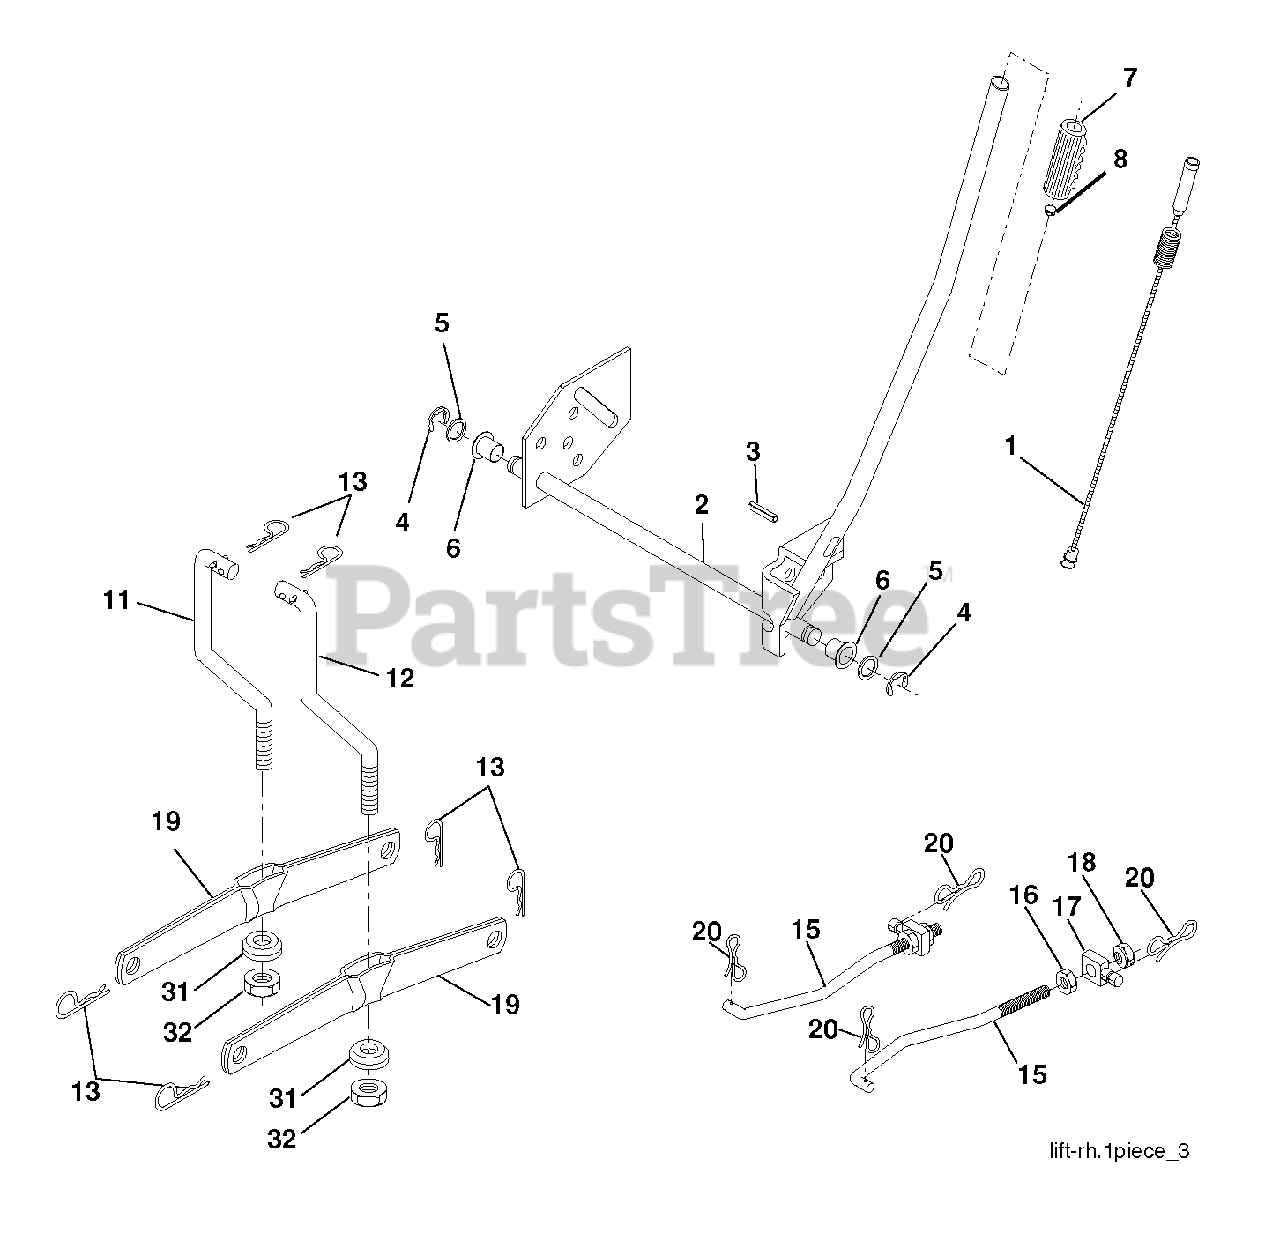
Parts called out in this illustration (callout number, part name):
1	PLUNGER.ASM.LIFT.LVR.B*SUBS/2*
2	SHAFT.ASM.LIFT.YT
3	Groove Pin, 5/16
4	RETAINING RING LT
6	BEARING.NYLON
7	GRIP
8	PLUNGER BUT KIT
11	LINK LIFT LH
12	LINK LIFT RH
13	RETAINER-SPRNG RB
15	LINK.SUSPENSION.FRONT
16	NUT
18	NUT
19	ARM.REAR.SUSPENSION
20	PIN.COTTER.7/16.BOW TI
31	BEARING.PIVOT.LIFT
32	NUT CROWNLOCK 3/8-24
